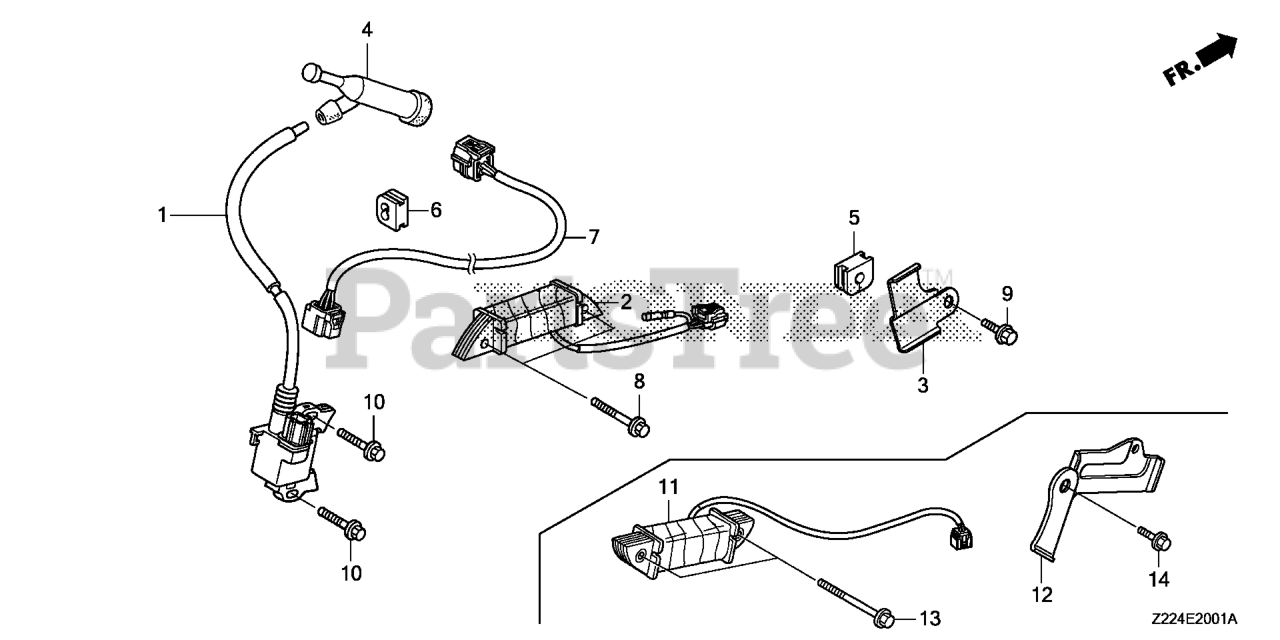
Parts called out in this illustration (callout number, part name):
1	COIL ASSY., IGNITION
1	COIL ASSY., IGNITION (IIDA)
2	COIL ASSY., POWER
3	BRACKET B, HARNESS
4	CAP ASSY., NOISE SUPPRESSOR (NGK Y-EZD)
5	GROMMET, WIRE
6	GROMMET, WIRE
7	WIRE HARNESS ASSY., ENGINE
8	BOLT, FLANGE (6X40)
9	BOLT, FLANGE (6X12) (CT200)
10	BOLT, FLANGE (6X28) (CT200) Use up to Engine SN 1530314.
